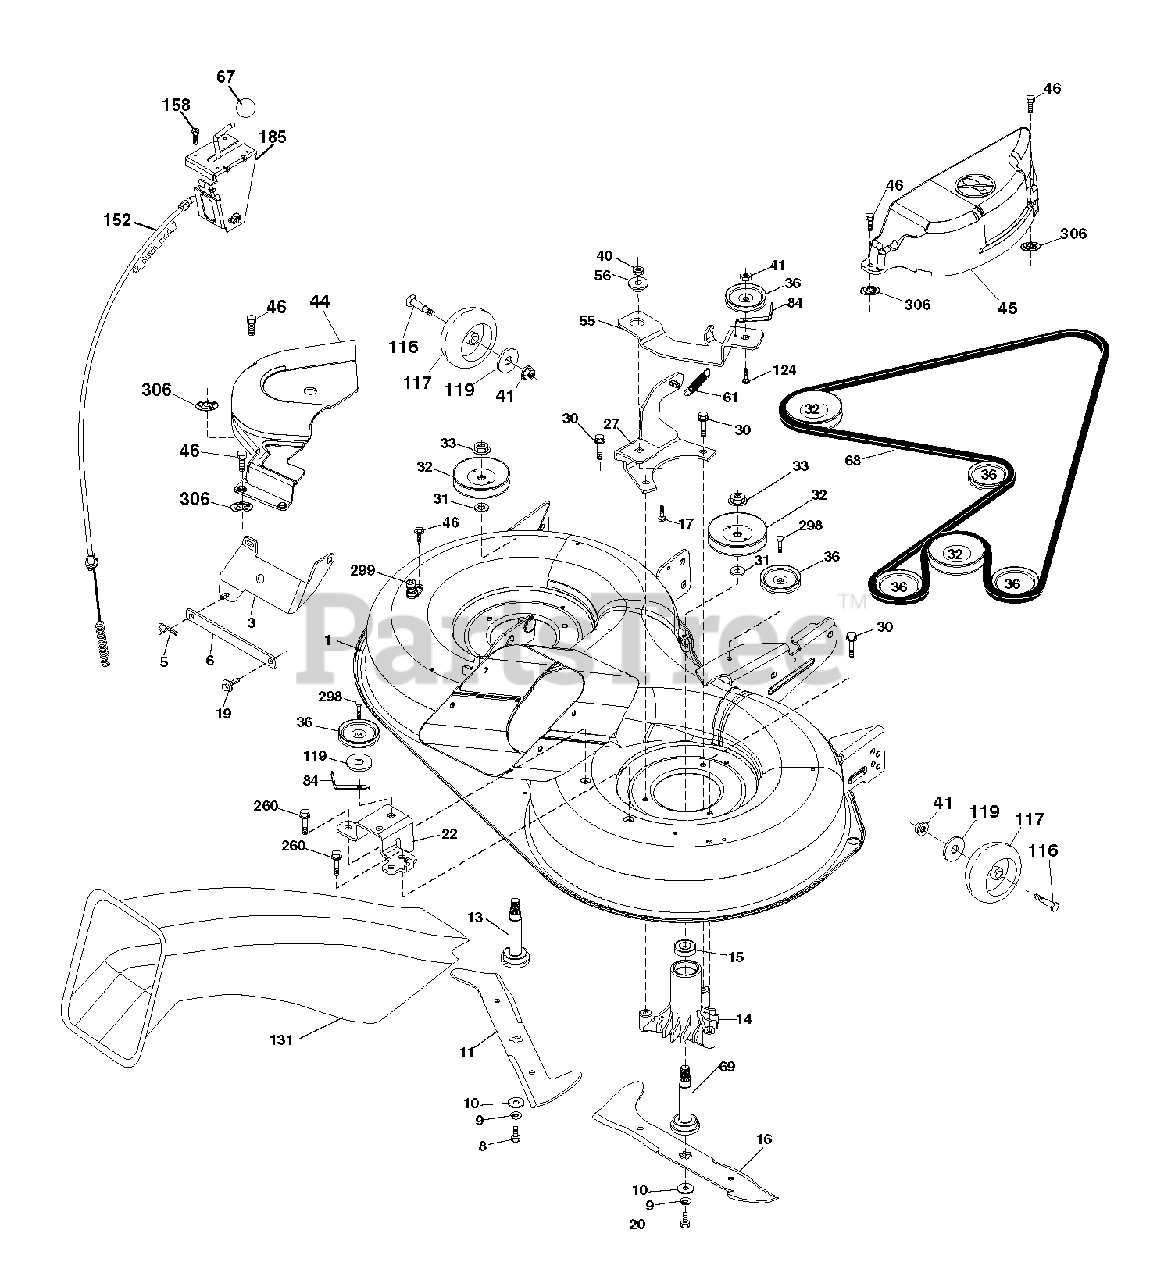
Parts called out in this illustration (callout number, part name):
1	DECK.WLDT.97.CRD.2GWB
3	BRACKET.ASM.BAR.SWAY.CHASS
5	RETAINER-SPRNG RB
6	BAR SWAY
8	Bolt, 3/8-24 X 1.25 Gr8
9	LOCKWASHER
11	BLADE.3N1.LH.CRD.97
13	SHAFT ASM VENT
16	BLADE.3N1.RH.CRD.97
17	BOLT.3/8-14X1.25
19	BOLT SHD 5/16-18
20	BOLT.3/8-24X1.25GR8. LHTHRD
22	BRACKET.SUPT.IDLER.REAR.RH
27	BRACKET.ASM.SUSP.REAR.RH.
30	SCREW, WASHER HEAD
31	WASHER.SPACER.MANDREL
32	PULLEY MANDREL
33	NUT.FLANGE.LOCK.TOP
36	PULLEY.IDLER.4.25
40	LOCKNUT
41	NUT LOCK FLG 3/8-16 UNC
44	OVER.MANDREL.LH.CRD
45	COVER.MANDREL.RH.97.CRD
46	SCREW.1/4-20X5/8
56	SPACER.RETAINER.MOWER
67	KNOB T (3/8 HOLE)
68	BELT.DRIVE.CRD.97.2010
69	SHAFT.ASM.W/LWR.BRG.RH.THREAD
84	KEEPER, BELT IDLER
116	BOLT.SHOULDER.3/8-16X3-5/8
117	WHEEL. GUAGE RALLY
124	BOLT.3/8-16X1.50
158	SCREW
185	HEAD ASM. CABLE CLUTCH
260	SCREW 3/8-16X1/2
298	SCREW LT
